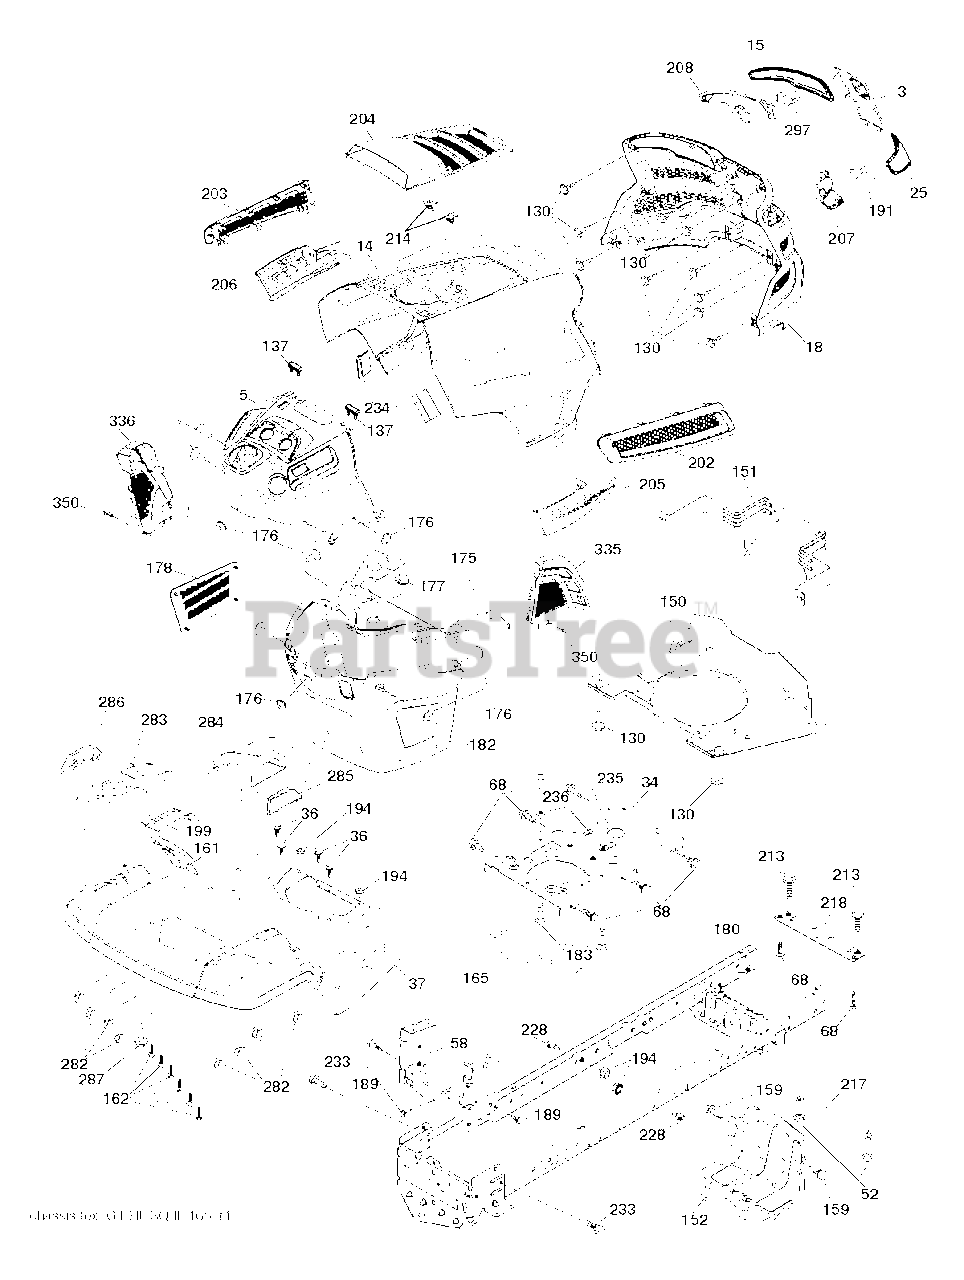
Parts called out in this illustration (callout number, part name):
3	APPLIQUE.SUBASM.GT.HUSQ.II
5	DASH.UPP.GT2.DUAL.RD.PTO.MCHOK
14	HOOD.ASM.HUSQVARNA.GT.TEX.ORAN
15	LENS.HEADLIGHT.LH.GTII.2011
18	GRILLE.SUBSTRATE.2011.
25	BEZEL LIGHT.RH.GT.II.MYLAR
34	PLATE.ENGINE.WELDED.CHASSIS
36	SCREW 5/16"
37	FENDER.TLT.FS.W/CPH/FW/RSF.668
52	LOCKNUT
58	DRAWBAR UPPER 2PC SMALL FENDER
68	SCREW LT
130	SCREW.#10 X 0.750.BOS
137	BUMPER DASH
150	AIR.DUCT.GTV.BLACK
151	BRACKET.PIVOT.HOOD.GT.HUSQ.II
152	SHIELD.BROWNING.PNT.GT.V2
159	SCREW, 3/8-16X3/4
161	WINDOW.FUEL.LT.HUSQ.TEX.498
162	SCREW.HI-LO.CONSOLE
165	SUPPORT.TANK.REAR.W/TEX
175	PLATE.CROSSMEMBER.HUSQ
176	SCREW.#10-24X5/8.RN.QU
177	BUSHING, STEERING
178	CARGO.ASM.NET.TXGT.W/C
180	CHASS.WLDMNT.TL.12GA/2P.48/54
182	DASH.LOWER.COMMON.12V.ADAPTOR
183	BOLT.5/16-18X1-1/4 FULL THD
189	SCREW
191	INSERT.REFLECTIVE.RH.HUSQ.GTII
194	NUT LOCK HEX FLANGE 5/16-18
199	PLATE.DECK.LIFT.HUSQ.LT
202	VENT.SIDE.RH.GT.HUSQ.II.
203	VENT.SIDE.LH.GT.HUSQ.II.498
204	VENT.TOP.HUSQ.GT2
205	SIDE.TRIM.RH.GT.HUSQ.II
206	BRACKET.MOUNT.CRUISE.LATCH
207	LENS.HEADLIGHT.RH.GTII.2011
208	LENS.HEADLIGHT.LH.GTII.2011
213	BOLT
214	CLIP.RETAINER.TINNER.
217	ROD.PIVOT.HOOD
218	X-PIECE.HOOD.STOP.NON/
228	STUD.FASTNER.W/ANTI-ROTATE
233	BOLT.SHOULDER
234	BUMPER.HOOD.TEX.HUSQVARNA
235	SPACER FENDER
236	NUT.CENTERLOCK.5/16-
282	CLIP.RETAINER.CONSOLE.LT.HUSQ
283	CONSOLE.DECK.LIFT.R.SDFL.HUSQ
284	CONCOLE.CNTRL.PDL.HUSQ.LT.498
285	CONSOLE INSERT RH
286	CONSOLE.INSRT.LH.HUSQ.LT.BLACK
287	SCREW 1/4X20
297	INSERT.REFLECTIVE.LH.HUSQ.GTII
335	COVER.LOWER.DASH.RH.BLACK
336	COVER-LH.LOWER.DASH.GT2.BLACK
350	CLIP.X-MAS.TREE
